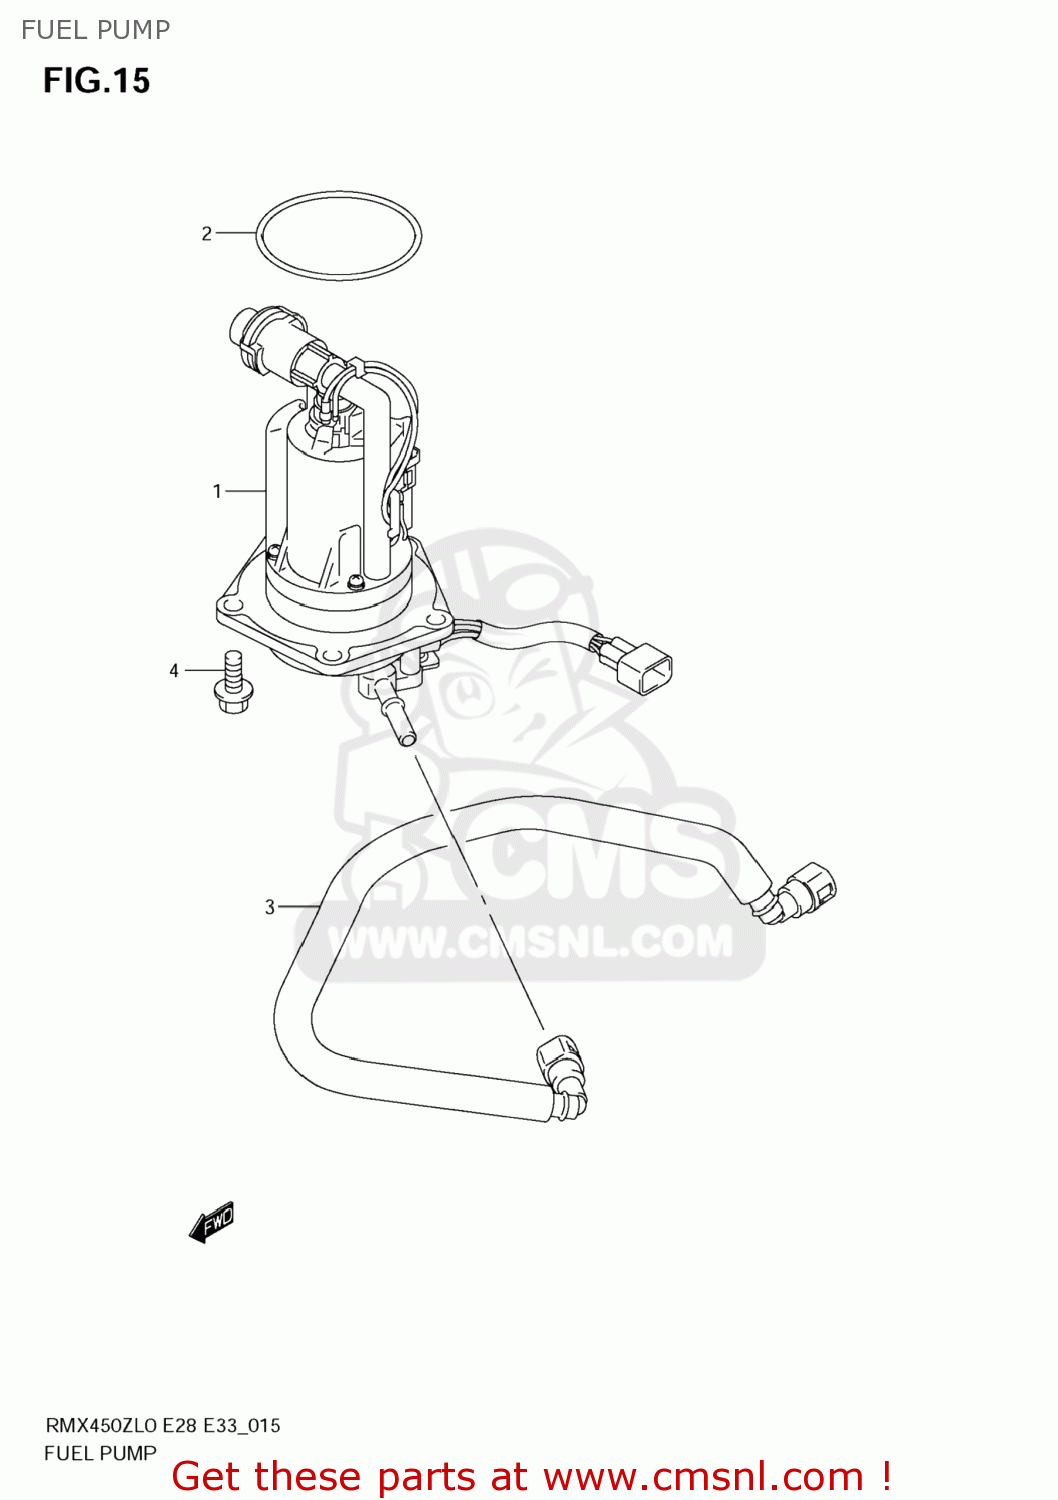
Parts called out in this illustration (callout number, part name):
1	PUMP ASSY,FUEL
2	O RING
3	HOSE,FUEL
4	BOLT
